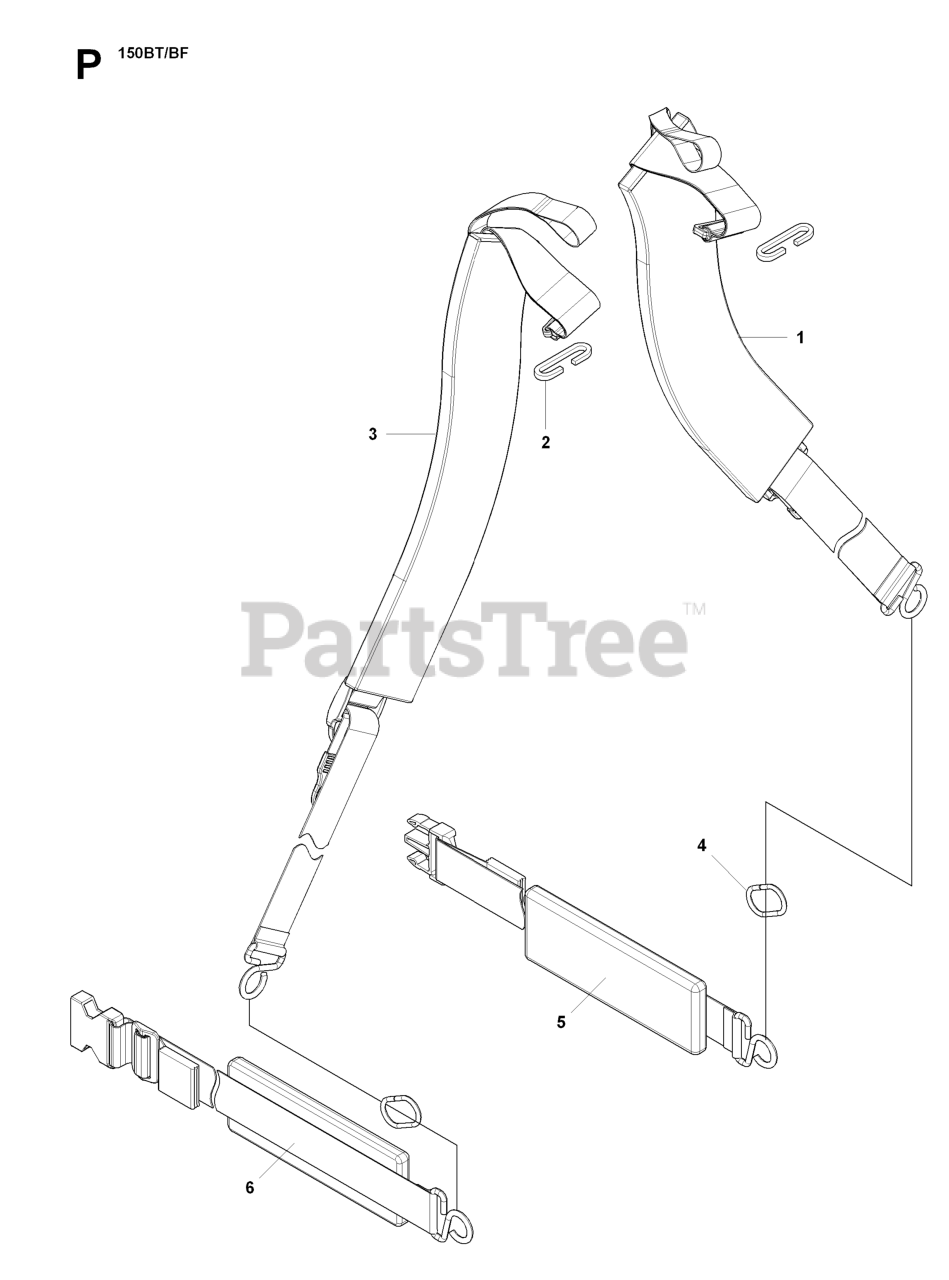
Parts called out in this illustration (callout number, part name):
1	BAND ASSY(R)
3	RP BAND ASSY (L)
4	RING
5	BAND B(R)
6	BAND B(L)
